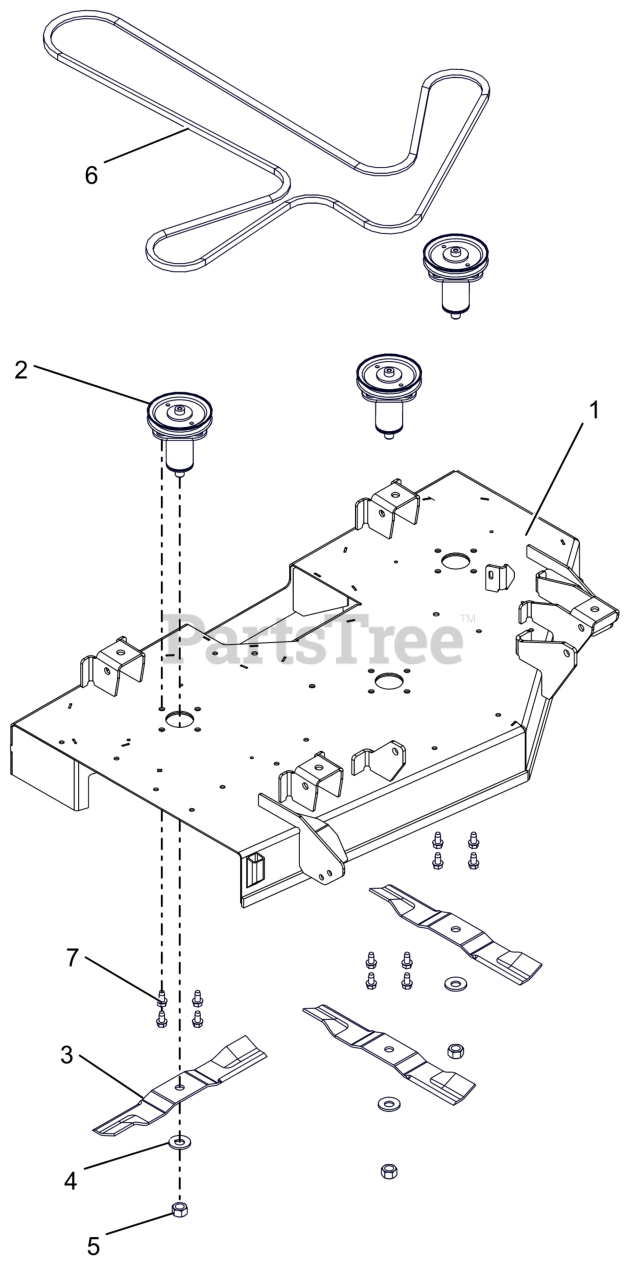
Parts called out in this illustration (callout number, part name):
1	KIT, 42" ARIENS DECK W/DECALS
2	KIT, DECK SPINDLE ASM-IKON-ZTX
3	BLADE, MOWER 15.00"
4	WSHR-BLVL .669X1.535X.138
5	NUT-STD .625-18 ZCC
6	V-BELT, 4L-WRAPPED
7	SCR,TAP .375-16X.75 HWH TR ZCC
